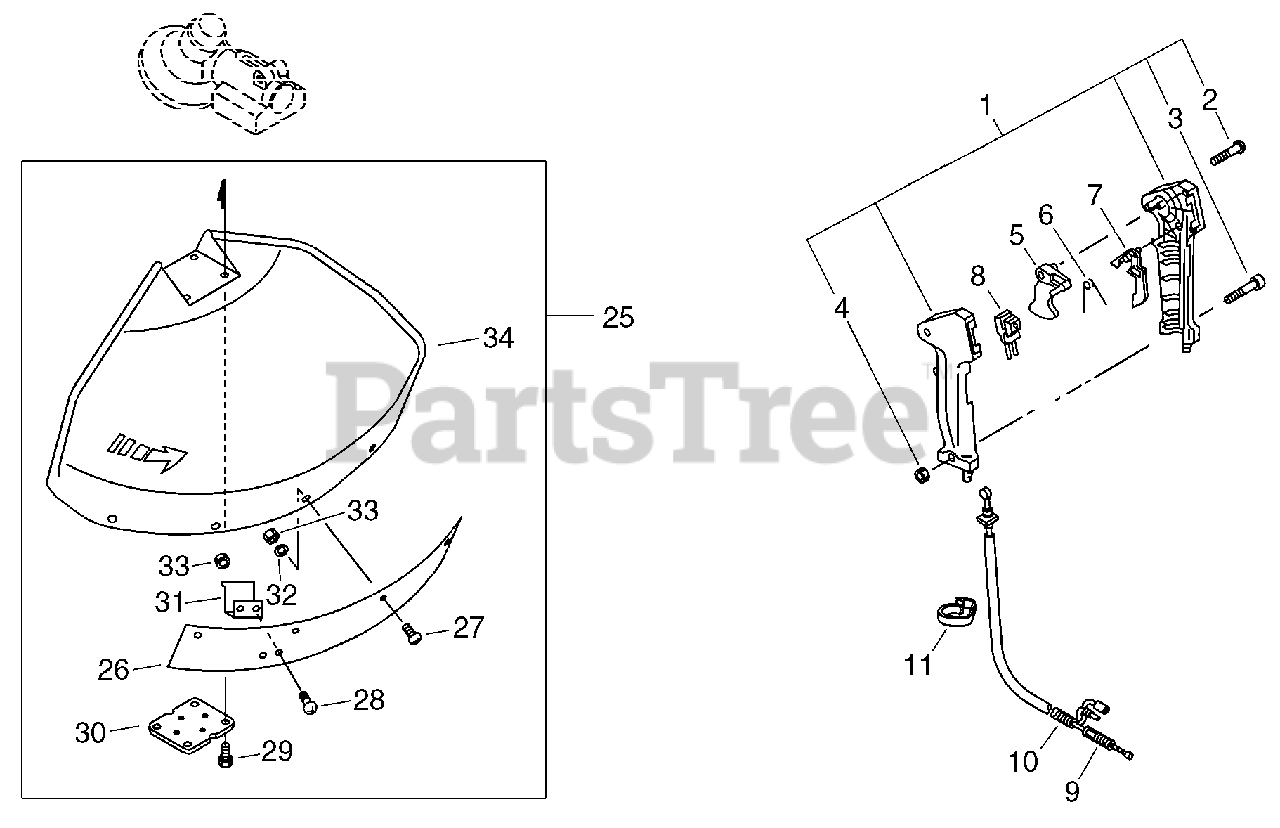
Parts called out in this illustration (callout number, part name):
1	THROTTLE CONTROL ASSY
2	SCREW - 3X25
3	SCREW - 5X30
5	TRIGGER, THROTTLE
6	SPRING, LOCKOUT LEVER
7	LOCKOUT, THROTTLE
8	IGNITION SWITCH ASSY
9	CABLE, THROTTLE
10	TUBE, PROTECTIVE - CORRUGATED
25	DEBRIS SHIELD ASSY
26	GUARD, SHIELD
27	SCREW - 5X18
28	SCREW - 5X14
29	BOLT - 5X25
30	BRACKET, SHIELD
31	KNIFE, TRIMMER LINE
32	WASHER - 5
34	SHIELD, DEBRIS
